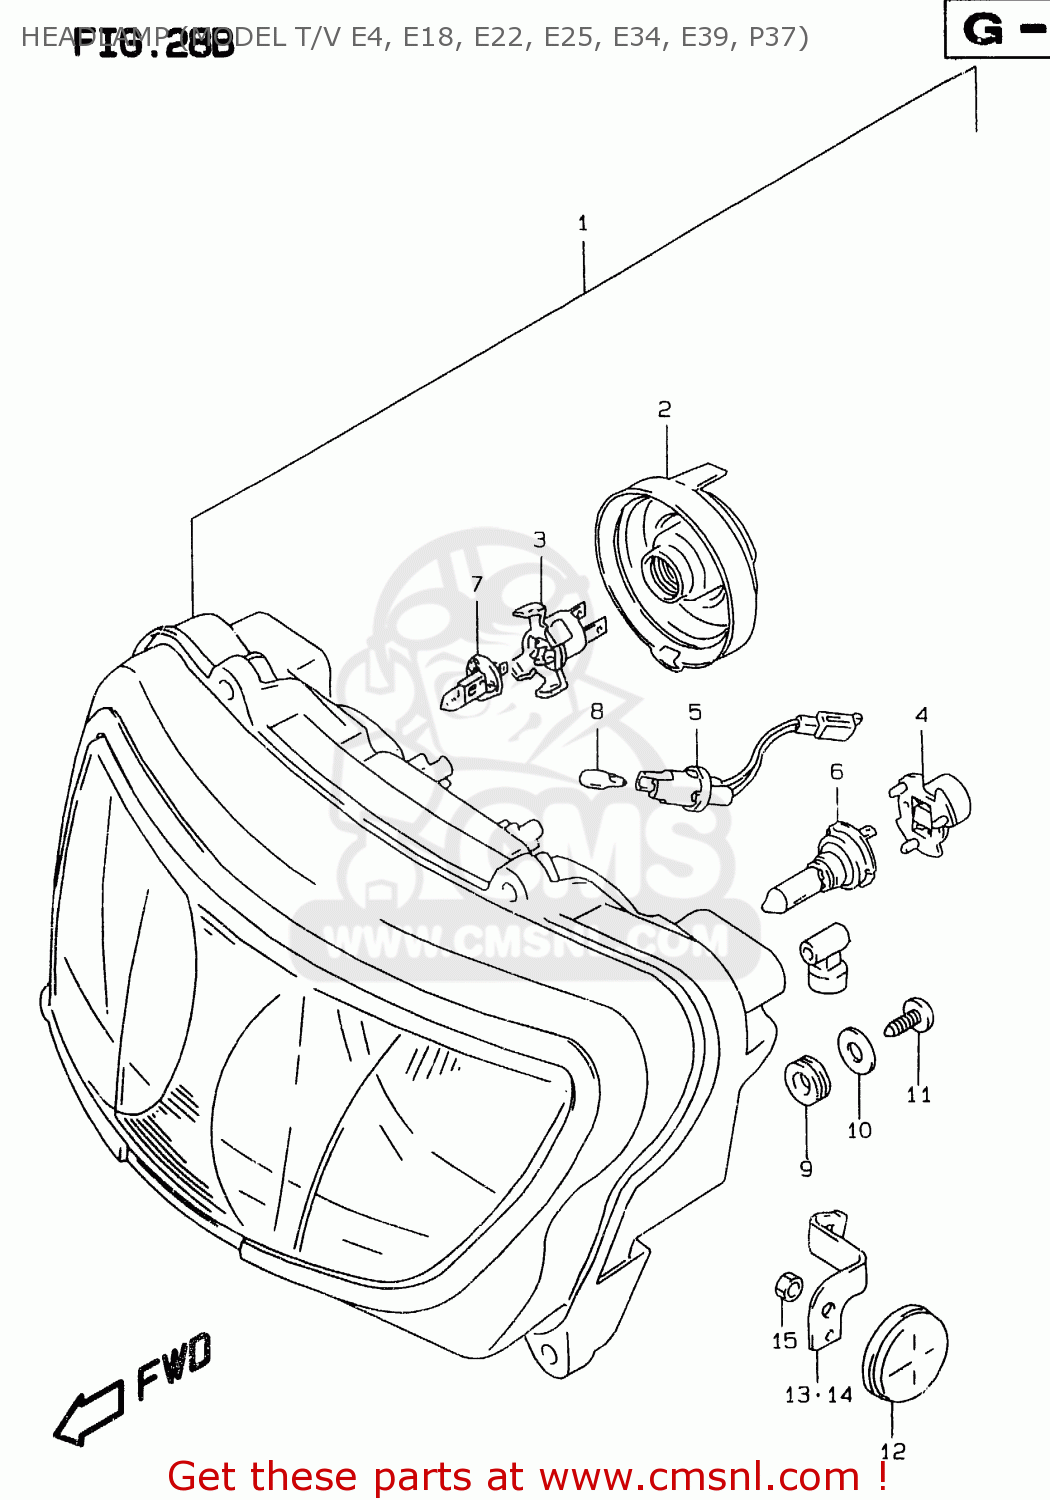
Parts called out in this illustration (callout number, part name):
1	HEADLAMP ASSY
2	COVER,SOCKET
3	ADAPTER ASSY
4	ADAPTER ASSY
5	SOCKET ASSY
6	BULB(12V55W/H7/PX26D/PHILIPS)
7	BULB(12V55W/H1/P14.5S/OSRA,PHI
8	BULB(12V5W)
9	CUSHION,HEADLAMP
10	WASHER(5.5X18X1)
11	SCREW,SIDE HOL
12	REFLECTOR,REFLEX FR
13	BRACKET,FR SIDE RR,R
14	BRACKET,FR SIDE RR,L
15	NUT
